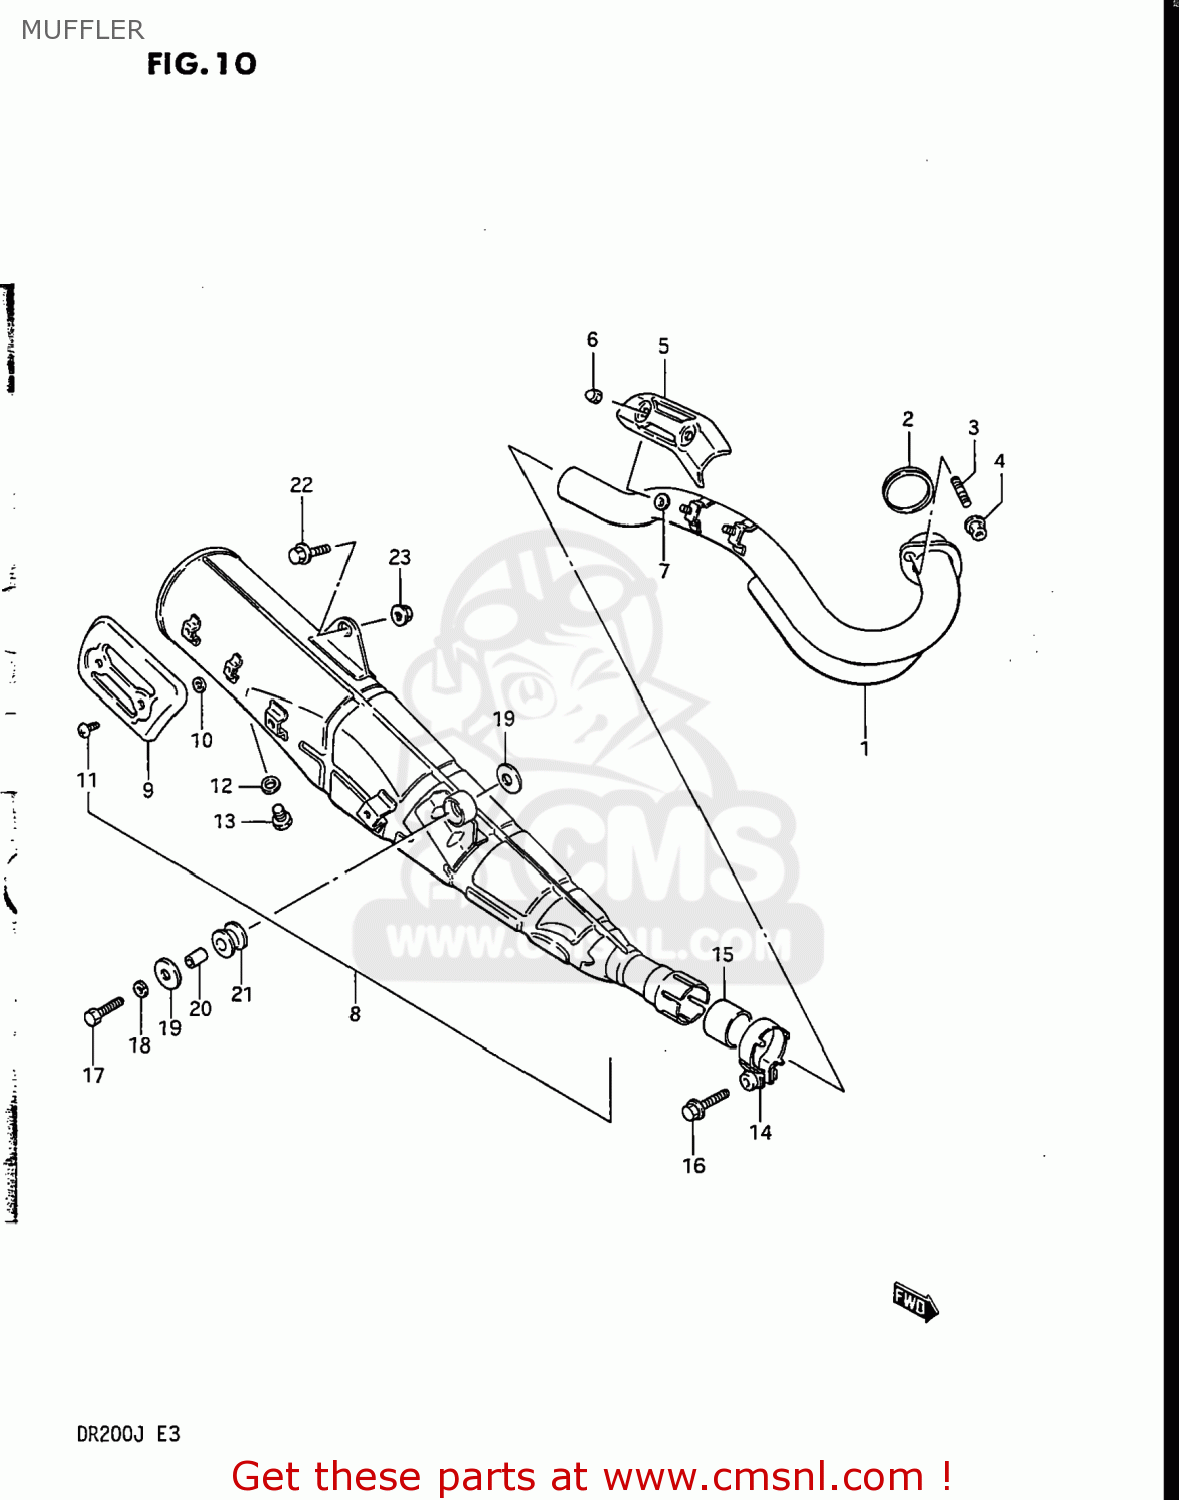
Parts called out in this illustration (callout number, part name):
1	PIPE COMP,EXHAUST
2	GASKET,EXHAUST PIPE (NAS)
3	BOLT,STUD
4	NUT
5	COVER,EXHAUST PIPE
6	NUT (6MM)
7	GASKET (NAS)
8	MUFFLER ASSEMBLY
9	COVER,MUFFLER
10	GASKET (NAS)
11	SCREW
12	GASKET(12.1X16.2X3.7) (NAS)
13	PLUG(12X9)
14	CLAMP,MUFFLER CONNECTOR
15	GASKET,SECOND MUFFLER (NA) (NAS)
16	BOLT
17	BOLT
18	WASHER,LOCK,8.
19	WASHER (8.5X20X1.6)
20	SPACER (8.6X12X17.5)
21	CUSHION
22	BOLT(8X25)
23	NUT
